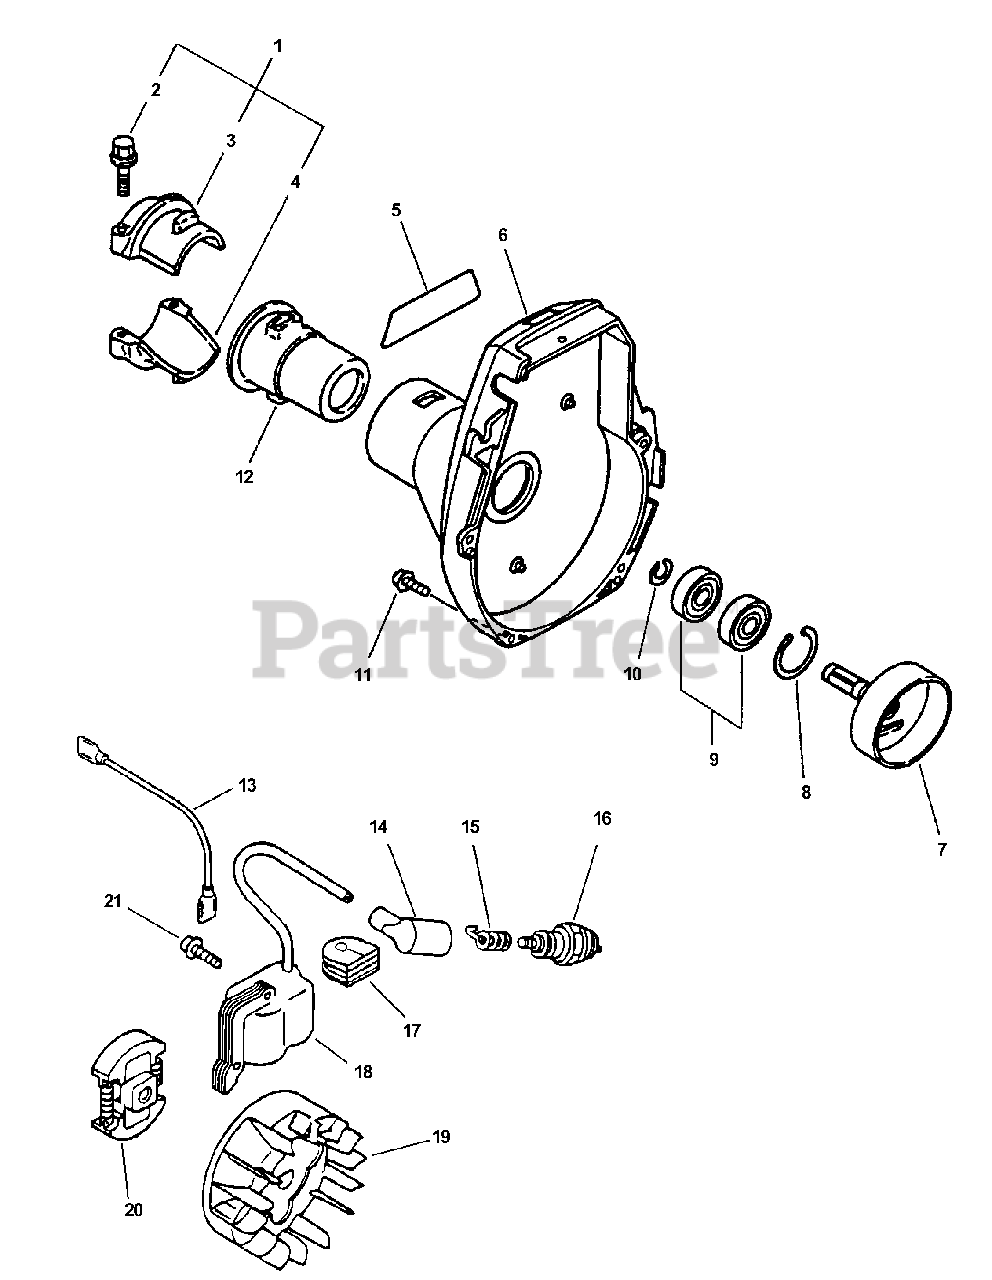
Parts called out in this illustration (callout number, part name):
1	RETAINER KIT
2	BOLT - 5×25
3	HOLDER, MAIN PIPE - UPPER
4	HOLDER - LOWER
5	LABEL, MODEL
6	COVER ASSY, FAN
7	DRUM, CLUTCH
8	RING, SNAP 28
9	BEARING, BALL 6001
10	RING, RETAINING - 12
11	BOLT 4×16
12	CUSHION Ø25
13	LEAD
14	CAP, SPARK PLUG
15	TERMINAL, SPARK PLUG
16	SPARK PLUG - BPM7A
18	COIL, IGNITION
19	FLYWHEEL
20	CLUTCH ASSY
21	SCREW 4×22
